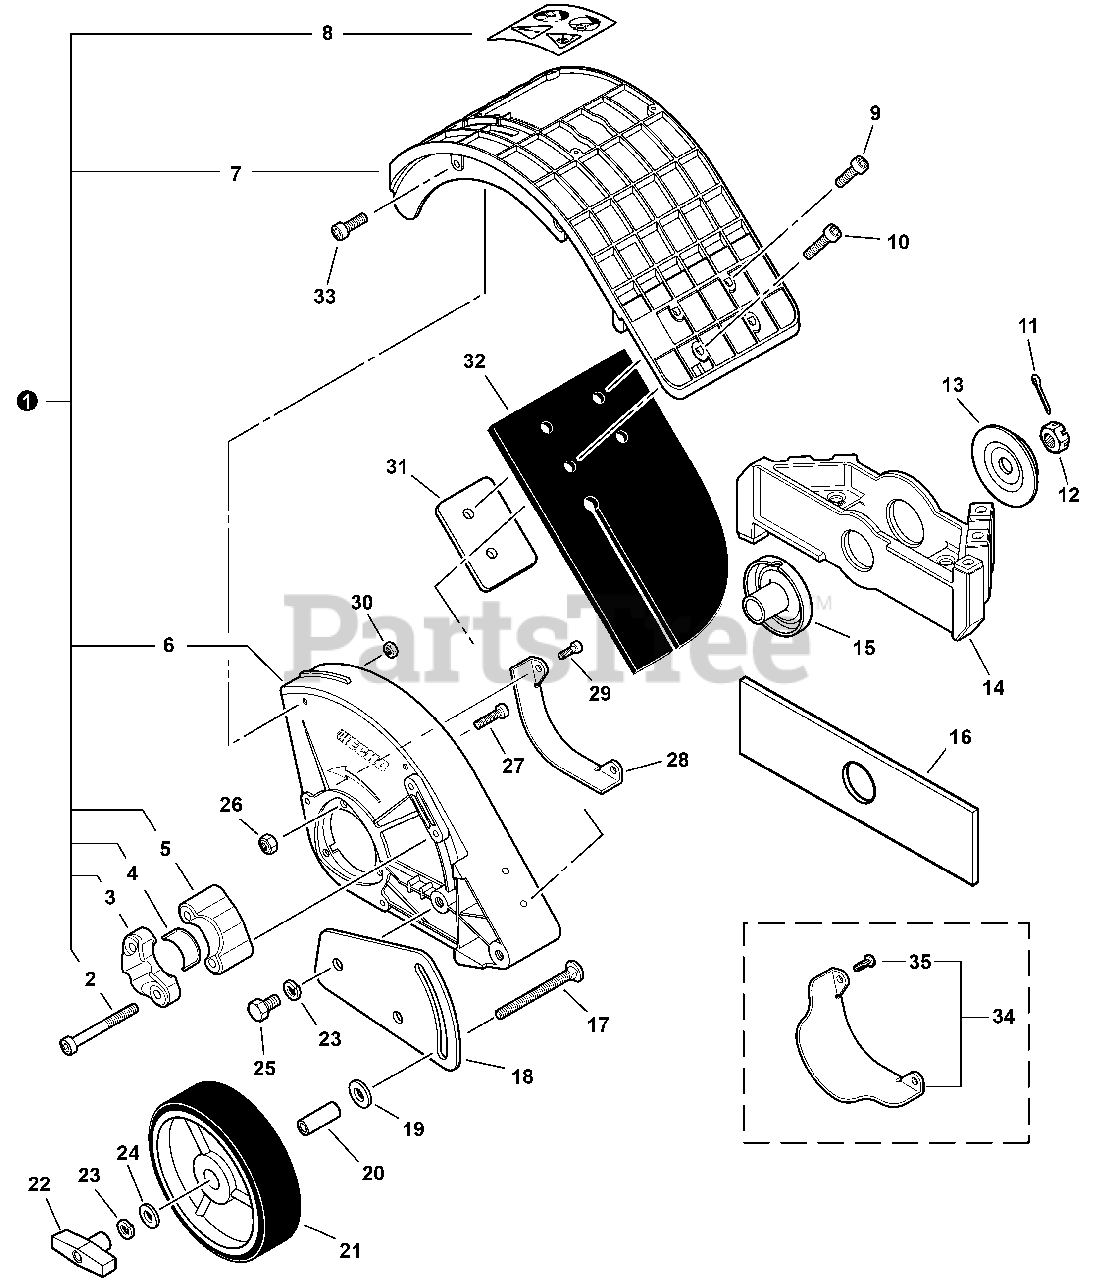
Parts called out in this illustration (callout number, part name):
1	DEBRIS SHIELD KIT
2	SCREW - 6×35
3	BRACKET - OUTER
5	BRACKET - INNER
6	SHIELD, BLADE
7	COVER, SHIELD
8	LABEL - CAUTION
9	SCREW - 4×12
10	SCREW - 4×16 -- TAPPING
11	PIN, SPLIT - 2×22
12	LOCKNUT - LEFT HAND
13	ADAPTER, BLADE - LOWER
14	BLADE, REDEFINING
15	ADAPTER, BLADE - UPPER
16	BLADE, EDGER
17	BOLT - CARRIAGE
18	BRACKET,WHEEL
19	WASHER - 10
20	COLLAR - 12
21	WHEEL - 6×1.5
22	WINGNUT - 5/16-18
23	LOCKWASHER - 8
24	WASHER - 8
25	BOLT - 8×14
26	LOCKNUT - 5
27	SCREW - 5×20
29	SCREW - 4×12
30	LOCKNUT - 4
31	PLATE, FLAP
32	FLAP, DEBRIS
33	SCREW - 4×12
34	SHIELD GUARD KIT
35	SCREW - 4x12 -- TAPPING
